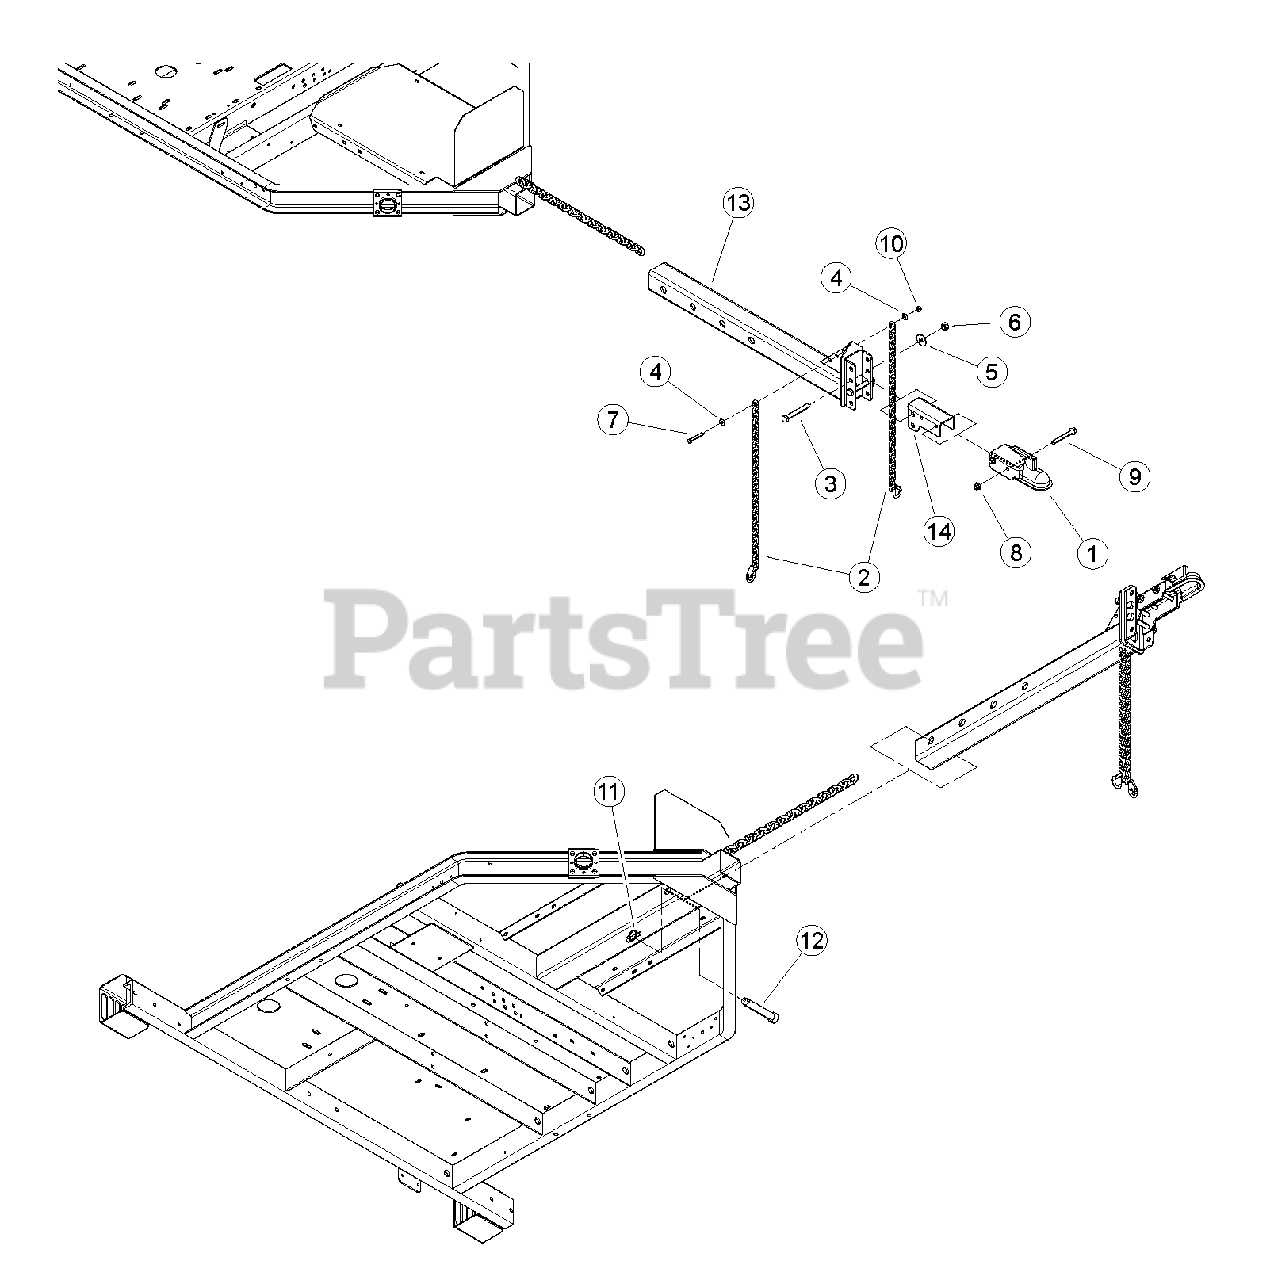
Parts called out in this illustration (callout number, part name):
1	COUPLER, 2 IN
2	CHAIN, SAFETY 5000 LB W/ LATCH
3	BOLT, 5/8 X 4-1/2 HEX HD G5 ZP
4	WASHER, 3/8" FLAT ZP
5	WASHER, 5/8" FLAT ZP
6	NUT, 5/8" CENTERLOCK ZP GR5
7	BOLT, 3/8 X 2-1/2 GR5 HHCS ZP
8	NUT, 1/2-13 NYLOCK FLANGE
9	BOLT, 1/2-13 X 4 HWH GR5 CZP
10	NUT, 3/8-16 NYLOCK FLANGE
11	PIN, 7/16 X 1-3/4 LYNCH
12	TOP LINK PIN, CAT 2
13	WELDMENT, HITCH POLE W/ PLATE
14	MOUNT, COUPLER
